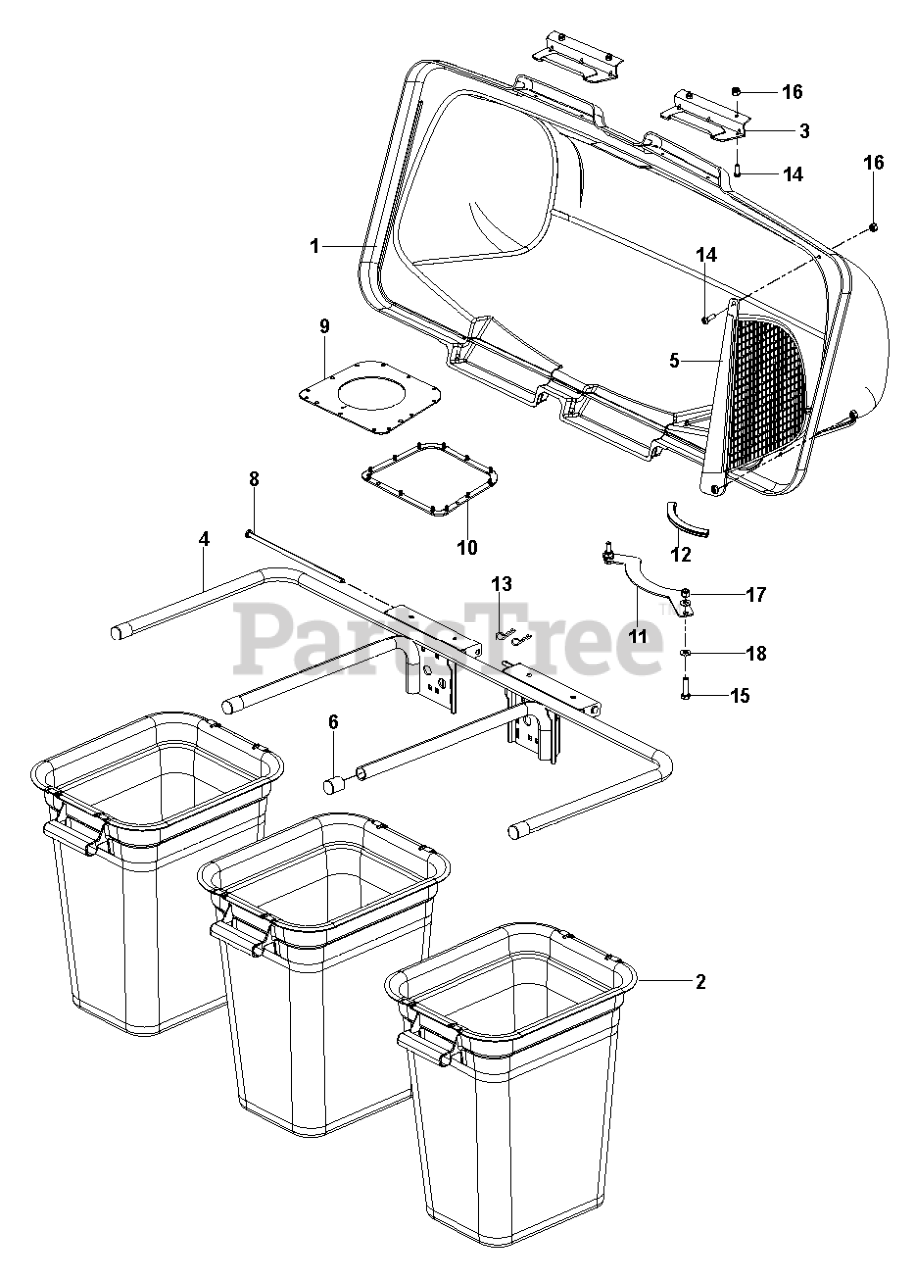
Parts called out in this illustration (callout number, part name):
1	COVER.ASM.3BIN.GENERIC.
2	CONTAINER BAG, SOFT
3	LATCH CER38
4	BAGGER, FRAME
5	SCREEN.COVER.BAGGER
6	TUBING PLUG
8	BAGGER.HINGE.PIN
9	SEAL.BAGGER.TOP.3-BIN.BLK
10	GASKET.COVER.BAGGER
11	SUPPORT.CHUTE.COLLECTION.BLACK
12	RP.FLEX TRIM, BLK-LENGTH 1 FT
13	RETAINER SPRING
14	SCREW #10-24 X 5/8
15	HCS 5/16C X 1 1/4
16	NUT 10-24 NYLOC
17	5/16-18 NYLOC FLANGE NUT
18	FLAT WASHER 5/16 SAE
